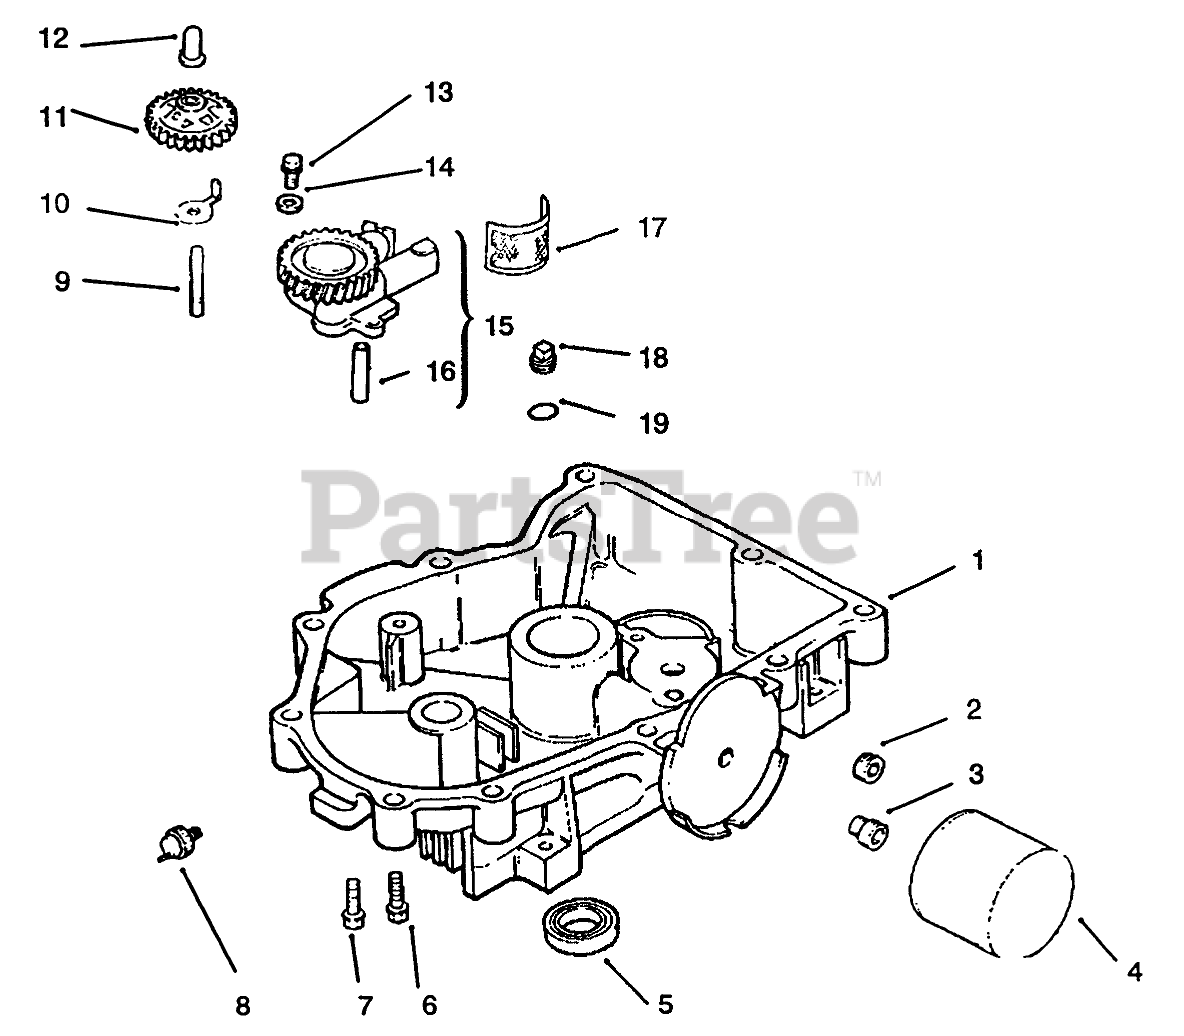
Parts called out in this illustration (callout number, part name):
1	Oil Pan (Only On: 72103, 72083)
2	Plug-HS 3/8 NPTF (Only On: 72103, 72083)
3	Nipple-Oil Filter (Only On: 72103, 72083)
4	Filter-Oil (Only On: 72103, 72083)
5	Seal-Oil (Only On: 72103, 72083)
6	Screw M8x1.25x45 (Only On: 72103, 72083)
7	Screw M8x1.25x45 (Only On: 72103, 72083)
8	Switch-Oil Pressure (Only On: 72103, 72083)
9	Shaft-Governor Gear (Only On: 72103, 72083)
10	Tab-Locking (Only On: 72103, 72083)
11	Governor Gear ASM (Only On: 72103, 72083)
12	Pin-Governor Regulating (Only On: 72103, 72083)
13	Screw-Valve Cover (Only On: 72103, 72083)
14	Washer-Governor (Only On: 72103, 72083)
15	Oil Pump ASM INC 16 (Only On: 72103, 72083)
16	Tube-Oil Pickup (Only On: 72103, 72083)
17	Screen-Oil Pickup (Only On: 72103, 72083)
18	Plug-SH 3/8 NPTF (Only On: 72103, 72083)
19	O-Ring (Only On: 72103, 72083)
